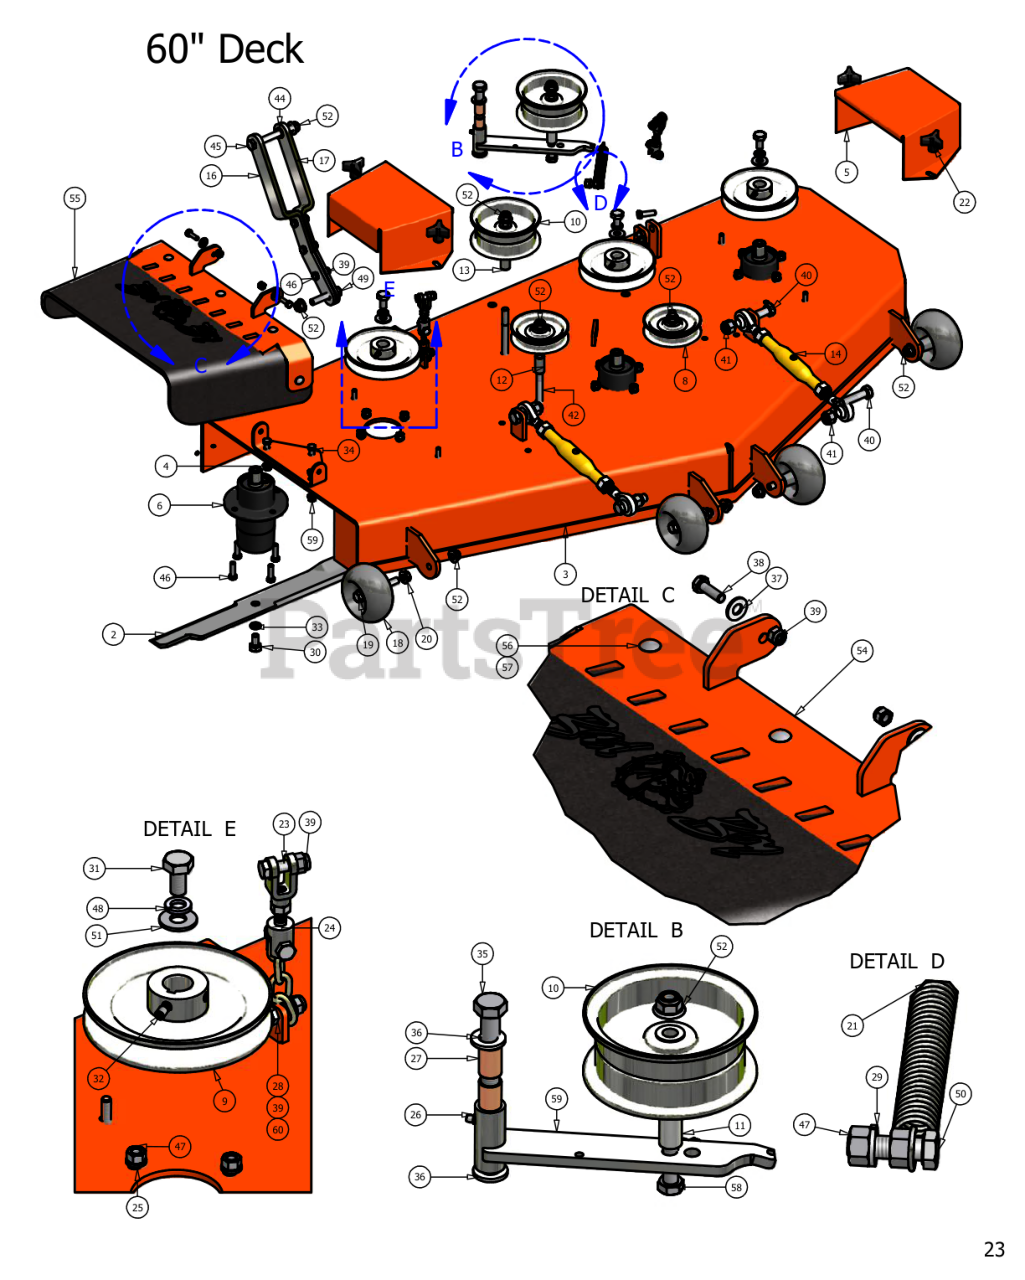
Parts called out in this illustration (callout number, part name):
1	60" Deck Belt
2	60" Fusion Blade
4	Discharge Chute Hanger
5	Pulley Guard
7	Deck Idler Arm
8	4 3/4" Idler Pulley
9	6 1/4" Drive Pulley
10	5 3/4" Flat Idler Pulley
11	1 1/4" Pulley Spacer
12	Pup Pulley Spacer
13	1 3/4" Pulley Spacer
14	Turnbuckle
15	3/4" Left Handed Nut
16	Deck Support Arm (left)
17	Deck Support Arm (Right)
18	Anti-Scalp Rollers
19	1/2" x 4" Bolt (Grade 8)
20	1/2" Flange Nut
21	Deck Idler Spring
22	5/16" Knob
23	Female Yoke
26	Grease Fitting (Drive-In Type)
27	5/8" ID x 1 1/8" Brass Bushing
28	3/8" x 1" Hex Bolt
29	3/8" Lock Washer
30	5/8" x 1.5" Fine Threaded Bolt
31	1/2" x 1 1/2" Bolt (Fine Threaded)
32	3/8" Set Screw
33	5/8" Lock Washer
34	3/8" x 3/4" Hex Bolt
35	5/8" x 4" Hex Bolt
36	.635 ID Plastic Washer
37	.360 ID Plastic Washer
38	5/16" x 1" Hex Bolt
39	5/16" Nylock Nut
40	5/8" x 2 1/2" Hex Bolt
41	5/8 Std NC Nylock Nut
42	1/2" x 3 1/2" Bolt
44	1/2" Brass Washer
45	1/2" x 4 1/2" Bolt
46	3/8" x 1 1/4" Hex Bolt
47	3/8" Hex Nut
48	1/2" Lock Washer
49	1/2" x 2 1/2" Hex Bolt
50	3/8" x 1 1/2" Hex Bolt
51	1/2" Cupped Washer
52	1/2" Flange Lock Nut
53	2007 Lower Hanger Plate
54	2007 Hanger Plate
55	Rubber Side Discharge
56	5/16" x 1 1/2" Carriage Bolt
57	5/16" Nylock Flange Nut
58	1/2" x 3" Bolt
59	3/8" Flange Nut
60	3/8" Flat Washer
